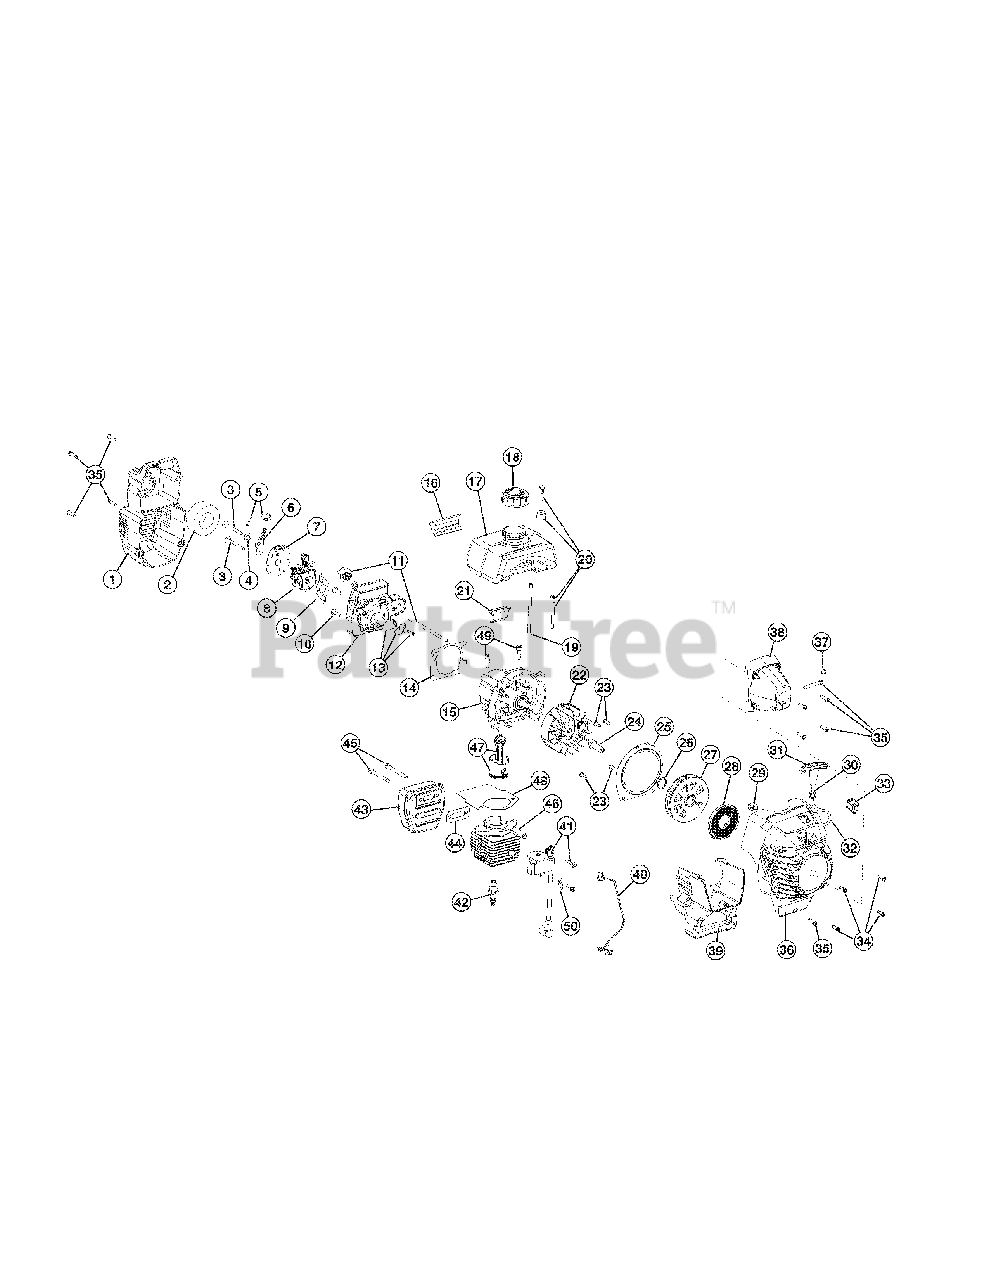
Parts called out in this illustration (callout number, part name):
1	Air Cleaner Cover Assembly (includes 2 & 35)
2	Air Cleaner Filter
3	Carburetor Mounting Screws
4	Wavey Washer
5	Choke Knob & Screw
6	Choke Lever Assembly (includes 5)
7	Choke Lever & Plate (includes 6)
8	Carburetor Assembly (includes 9 & 20)
9	Carburetor Gasket
10	Carb Mount Screw
11	Primer and Hose Assembly
12	Carburetor Mount Assembly (includes 10, 13 & 14)
13	Reed Assembly
14	Carburetor Mount Gasket
15	Crankcase Service Assembly (includes 10 & 23)
16	Rear Mounting Pad
17	Fuel Tank Assembly (includes 18 & 20)
18	Fuel Cap Assembly
19	Fuel Return Line
20	Fuel Line Assembly
21	Front Mounting Pad
22	Flywheel Assembly
23	Screw
24	Square Nut Drive
25	Pulley Retainer Assembly (includes 23 & 29)
26	Palnut
27	Recoil Pulley Assembly (includes 26 & 32)
28	Recoil Spring
29	Rope Guide Retainer
30	Pull Handle
31	Rope Guide
33	Switch Assembly (includes 40)
34	Housing Screw
35	Cover Screw
36	Starter Housing Assembly (includes 23, 25-32, 34 & 35)
37	Anti-Rotation Screw
38	Clutch Cover Assembly (includes 35 & 37)
39	Shroud Extension and Stand (includes 35)
40	Wire Lead
41	Module Assembly
42	Spark Plug
43	Muffler Assembly (includes 44 & 45)
44	Exhaust Gasket
45	Muffler Mounting Bolt Assembly
46	Cylinder Assembly (includes 48 & 49)
47	Piston & Rod Assembly
48	Cylinder Gasket
49	Cylinder Bolt
50	Ground Tab
